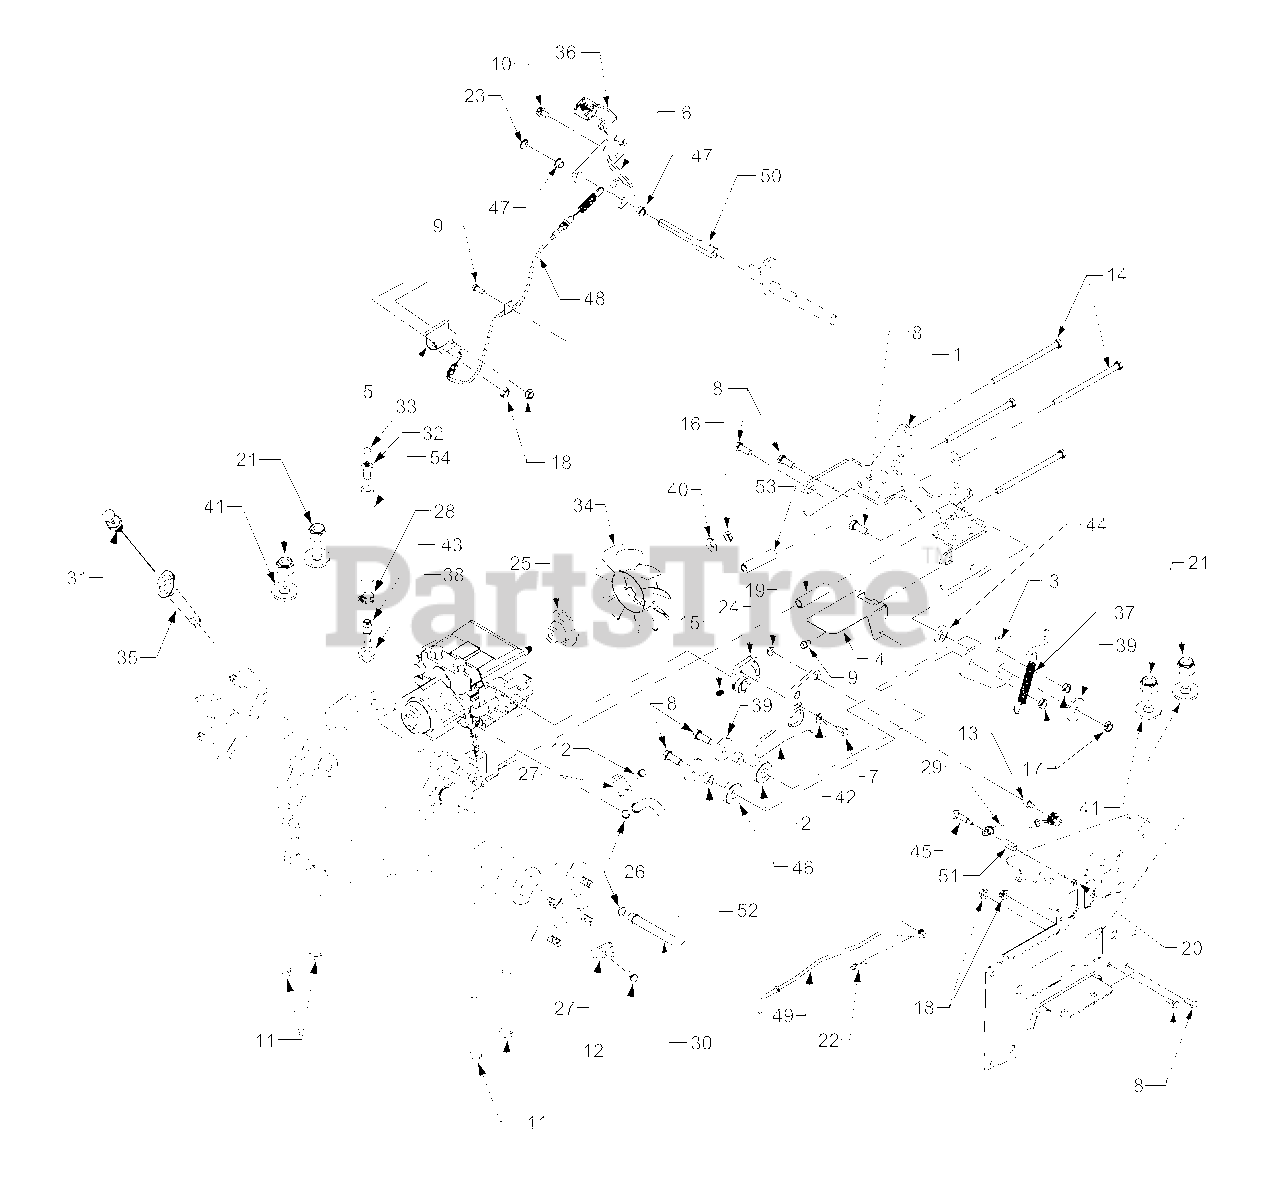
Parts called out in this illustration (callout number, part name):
1	Bracket, Torque
2	Plate, Hydro Neutral Return
3	Link, Neutral Return Bearing
5	Bracket, Cable Retainer
6	Bracket, Pedal Brace
7	Screw, Hex Cap, 1/4-20 x .625 GR5 Lock
8	Screw, Hex Cap, 3/8-16 x 1.0 GR5
9	Screw, Hex Wash. Hd. Tapp, 1/4-20 x .5
10	Screw, Hex Wash. Hd. Tapp, 3/8-16 x .75
11	Screw, Hex Cap, 1/2-20 x 4.5 GR5
12	Screw, Hex Cap, 1/4-20 x .75 GR5
13	Ball Screw, 5/16-18 x .56
14	Screw, Hex Wash. Hd. Tapp 5/16-18 x 5.5 GR5
15	Screw, Set, 5/16 x .5
16	Nut, Hex Top Lock Jam, 1/2-20
17	Nut, Hex Ctr. Lock Jam, 3/8-16
18	Nut, Hex Flange Lock, 3/8-16
19	Nut, Hex Flange Lock, 5/16-18
20	Nut, Hex, 1/4-20
21	Nut, Hex Insert Lock, 1/2-20
22	Pin, Internal Cotter
23	E-Ring, .5 Dia. Shaft
24	Arm, Hydro
25	Adapter, Pump
26	O-Ring, .426 ID x .566 OD x .070
27	Clamp, Tube
28	Clamp, Hose
29	Cylinder, Damper
30	Tube, Hydro Pickup
31	Dipstick, Transmission
32	Plastic Vent
34	Fan, Pump
35	Holder, Dipstick
36	Pedal, Diff Lock
37	Spring, Extension
39	Washer, Flat, .390 x 1.5 x .1
40	Washer, Bell, .5 x 1.0 x .05
41	Washer, Flat, .531 x 1.062 x .134
42	Washer, Flat, .26 x .72 x .06
43	Fitting, Tube
44	Spacer, Shoulder
45	Shoulder Bolt
46	Bearing, Ball
47	Bearing, Nylon Flange
48	Cable, Diff Lock
49	Rod, Pump Bypass
50	Shaft, Diff Lock
51	Spacer, .375 x .5 x 1.02
52	Spacer, .375 x .624 x .445
53	Spacer, Hydro, .3223 x .60 x 2.44
